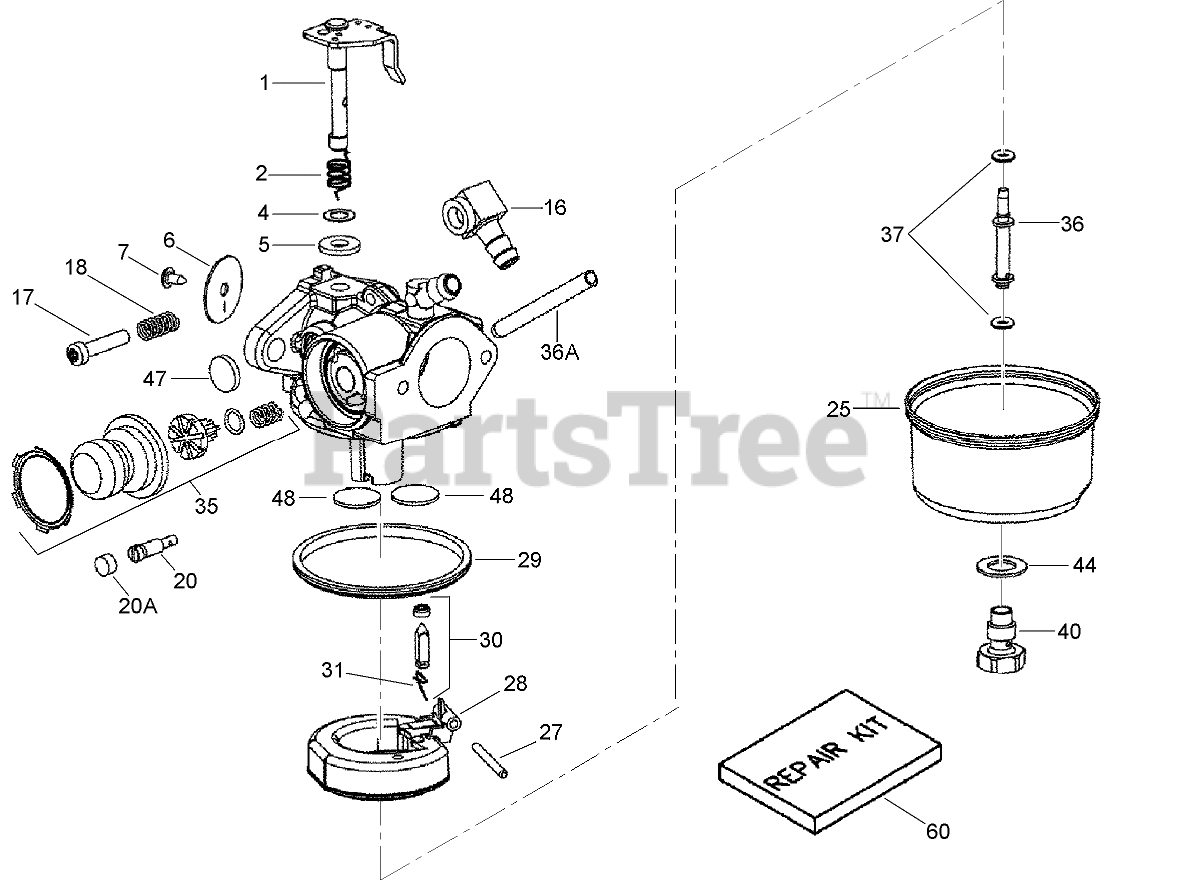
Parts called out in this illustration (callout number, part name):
1	Throttle Shaft and Lever ASM
2	Spring-Return, Throttle
4	Washer-Seal, Dust
5	Seal-Dust
6	Shutter-Throttle
7	Screw-Shutter
16	Fitting-Fuel
17	Screw-Throttle Crack and Idle Speed
18	Spring-Tension
20	Screw-Restrictor, Idle
20A	Cap-Screw, Restrictor Idle
25	Bowl-Float (no drain)
27	Shaft-Float
28	Float (Plastic)
29	O Ring-Bowl, Float
30	Inlet Needle, Seat and Clip ASM (Includes 31)
31	Clip-Spring
35	Primer Bulb and Valve Repair Kit
36	Tube-Nozzle, Main
36A	Tube-Carburetor
37	O-Ring
40	Nut-Bowl, High Speed
44	Washer-Nut, Bowl
47	Plug-Welch, Idle Mixture Well
48	Plug-Welch, Atmospheric Vent
60	Carburetor Repair Kit
